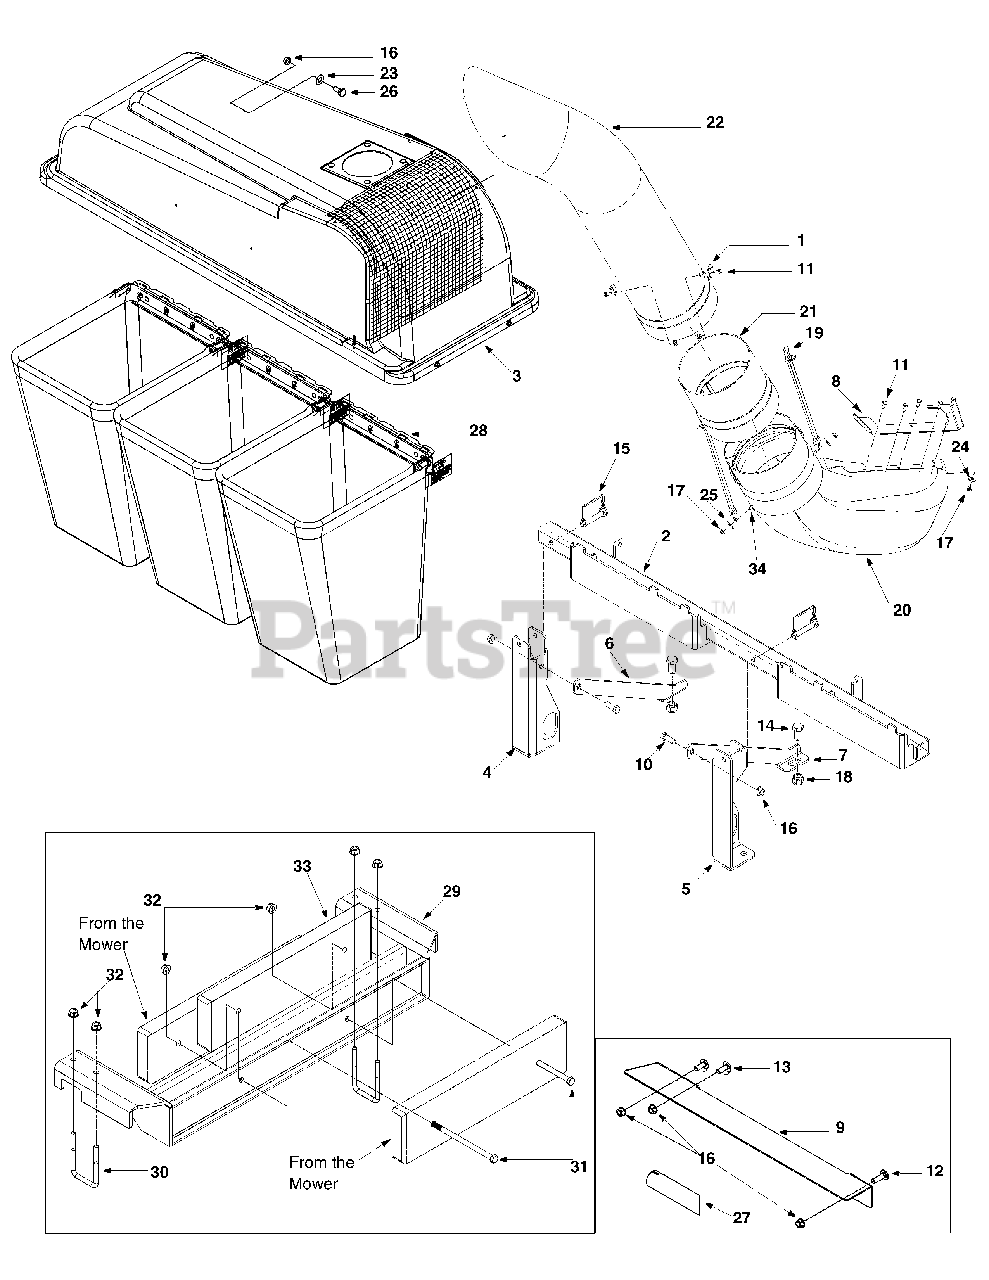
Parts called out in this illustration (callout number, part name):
1	Retainer Hook
10	Hex Bolt 3/8-16 x 1.0"
11	Hex Bolt 1/4-20 x 0.620"
12	Carriage Bolt 3/8-16 x 1.25"
13	Carriage Bolt 3/8-16 x 1.0"
14	Hex Bolt 1/2-13 x 1.0"
15	Lock Pin
16	Top Lock Flange Nut 3/8-16
17	Flange Lock Nut 1/4-20
18	Lock Nut 1/2-13
19	Chute Strap
20	Chute Elbow
21	Extension Tube
22	Chute Tube
23	Beleville Washer
24	Bell Washer
25	Flat Washer
26	Shoulder Screw 3/8-16
27	Exhaust Pipe: Kawasaki
28	Grass Bag
31	Hex Bolt 3/8-16 x 6.25"
32	Top Lock Flange Nut
33	Weight Bar
34	Hex Bolt 1/4-20 x 1"
